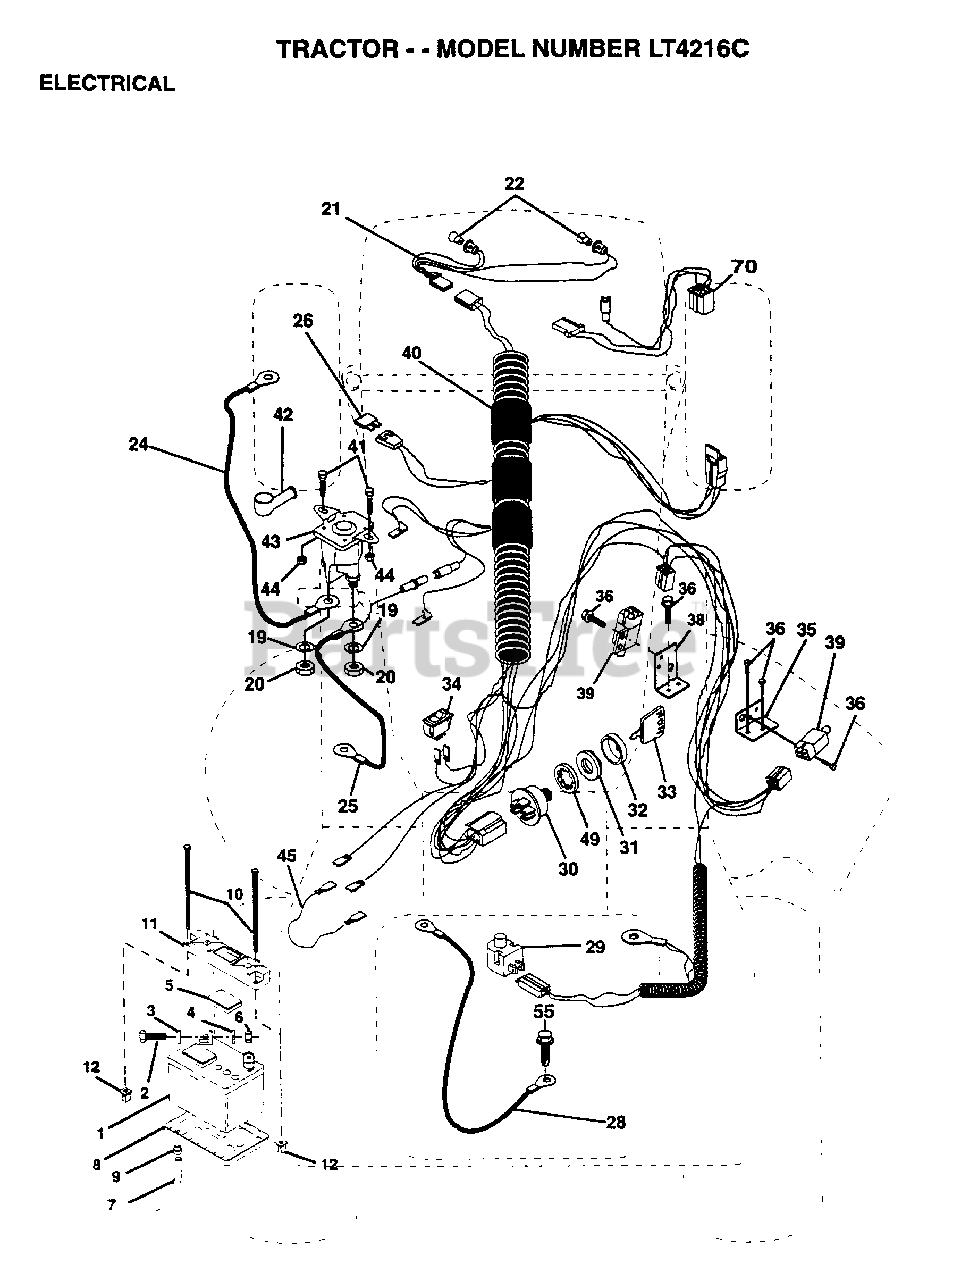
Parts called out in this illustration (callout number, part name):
2	BOLT LT
3	WASHER
4	LOCKWASHER
5	"CAP,BATTERY "
7	"DRAIN TU T, BATT"
8	"TRAY T, BATTERY"
9	HOSE CLAMP T
20	NUT
21	"HARNESS,LIGHT SOC"
22	HEADLAMP BULB
24	CABLE-BATTERY T
25	CABLE.6GA.22W/16W
26	FUSE HYT
28	CABLE.GRND.6GA.21
29	SWITCH SEAT
32	COVER KEY SWITCH
33	KEY MLD GEN DELTA
34	SWITCH LT
35	BRACKET LT
36	SCREW
38	BRACKET SWITCH IN
39	SWITCH INTERLOCKT
40	HARNESS.IGN.DASH.
41	BOLT.HX.1/4-20
44	NUT
45	ADAPTER AMMETER
49	LOCKWASHER
55	SCREW LT
70	HARNESS ENG DUAL
